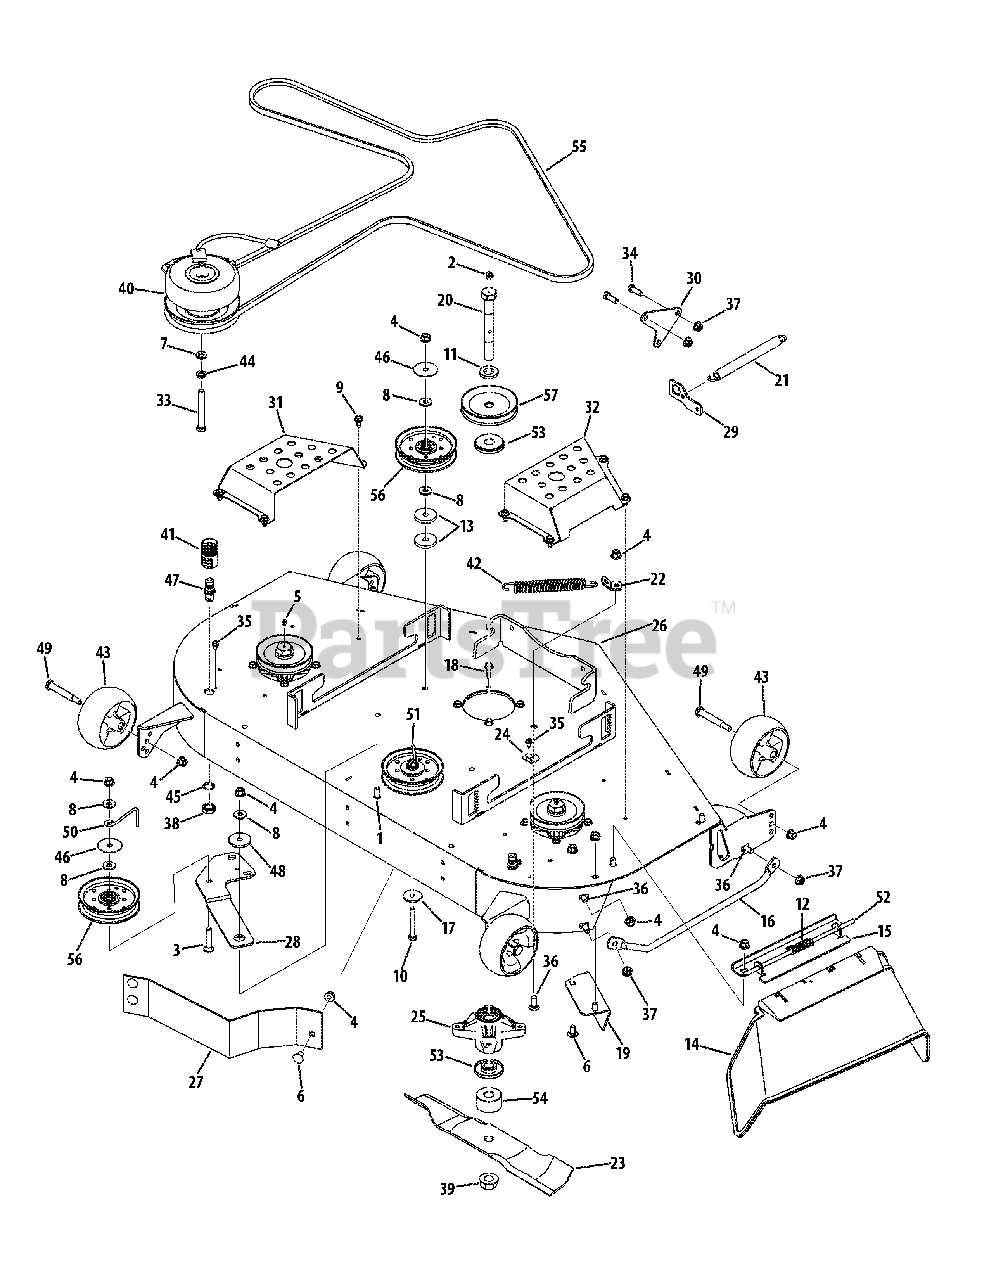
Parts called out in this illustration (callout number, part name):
1	Hex Screw, 3.8-16 x 2.50
2	Grease Fitting, 1.4-28 x .788
3	Carriage Bolt, 3.8-16 x 2.00
4	Counterlock Flange Nut, 3.8-16
5	Straight Grease Fitting, 1.4-28
6	Carriage Bolt, 3.8-16 x .75
7	Washer, .469 x .875 x .105
8	Washer, .406 x 1.00 x .105
9	TT Screw, 5.16-18 x .625
10	Hex Screw, 3.8-16 x 2.75
11	Spacer, .812 x 1.47 x .218
12	Torsion Spring
13	Washer, .438 x 1.75 x .250
14	Fab Deck Deflector Chute
15	Deflector Chute Bracket
16	Fab Deck Chute Finger Guard
17	Washer, .390 x 1.50 x .122
18	Flange Hex TT Screw, 5.16-18 x 1.00
19	Micro Chute Baffle
20	Hex Screw, 3.4-16 x 6.00
21	Hook Ext. Spring, .75 x 7.89 x .14
22	45-Degree Spring Mount Bracket
23	Hi-Lift Blade, 17.0
24	Retainer Hook Bracket
25	Deck Spindle Assembly
26	48" Welded Deck
27	48" Standard Baffle
28	48" Plate Idler
29	Spring Mount Bracket
30	Spring Mount Plate
31	48" LH Belt Cover
32	48" RH Belt Cover
33	Hex Screw, 7.16-20 x 3.50
34	Hex Screw, 3.8-16 x 1.00
35	Hex Washer TT Screw, 1.4-20 x .500
36	Carriage Bolt, 3.8-16 x 1.00
37	Flange Lock Nut, 3.8-16
38	Hex Nut, M16-1.5
39	Flange Lock Nut, 3.4-16
40	Electric PTO Clutch
41	Water Nozzle Adapter
42	Extension Spring, .91 x 7.33
43	Deck Wheel, 5.0
44	Lock Washer, 7.16
45	Lock Washer, 17 x 23.8 x 1.95
46	Flat Washer, .406 x 1.92 x .060
47	Water Deck Nozzle
48	Shoulder Spacer, .884 x .190
49	Shoulder Bolt, 3.8-16 x .496 x 2.50
50	Belt Keeper Rod
51	Belt Keeper Rod
52	Chute Deflector Rod
53	Deck Spindle Spacer
54	Spindle Spacer, .76 x 2.0 x 1.1
55	Hi-Performance Belt
56	Idler Pulley
57	V-Type Pulley
